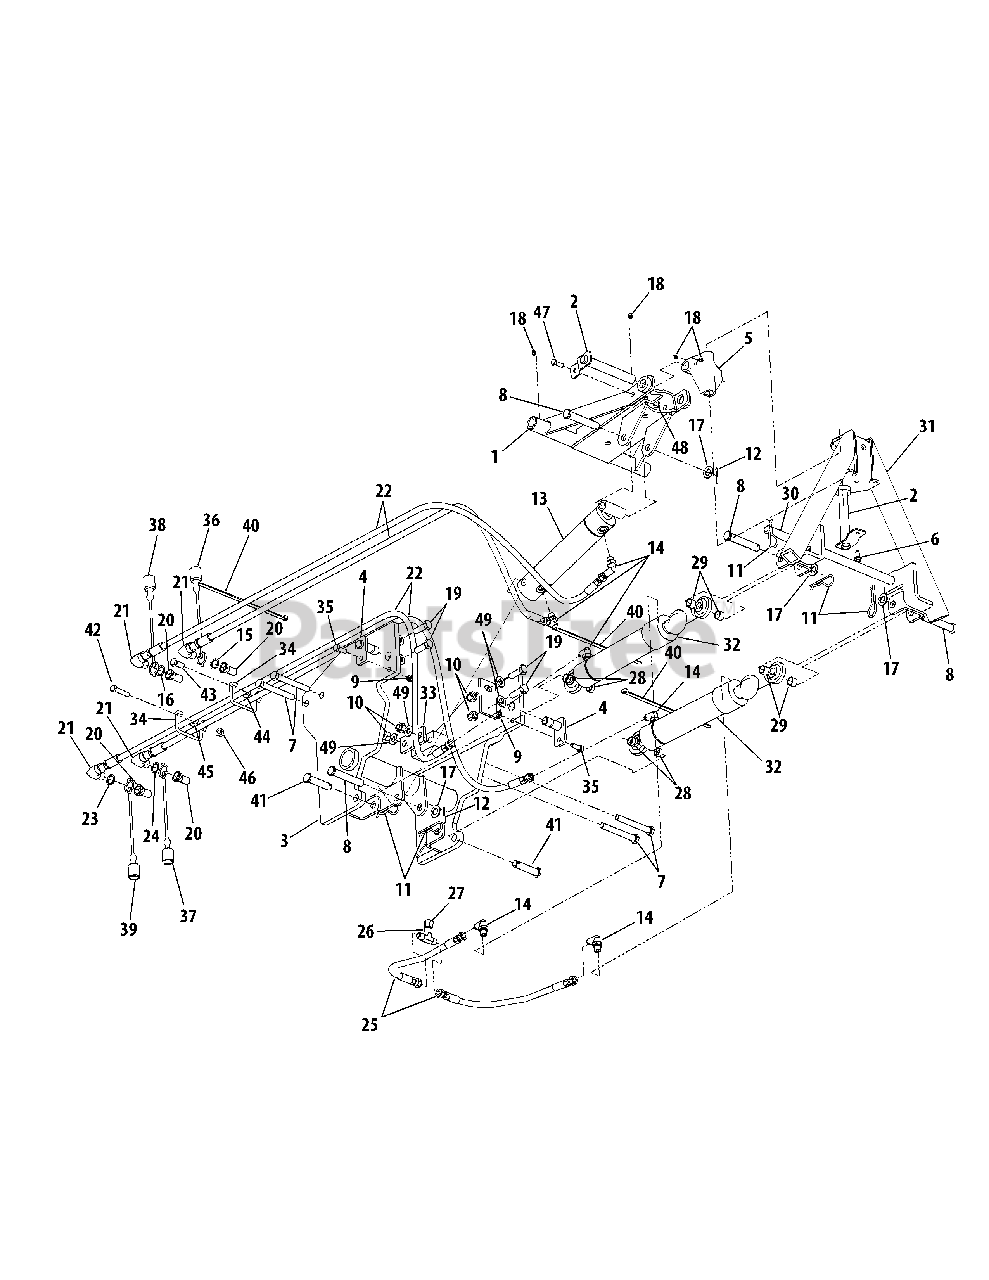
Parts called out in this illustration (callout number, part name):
2	Pin, Front Hitch
3	Brace, Front Hitch
4	Pin, Hitch Pivot
5	Housing, Pivot
6	Screw, Hex Wash. Hd Tap, 5/16-18 x .75
7	Screw, Hex Cap, 1/2-13 x 4.0 Gr5
8	Pin, Clevis, .625 x 3.45
9	Screw, Hex Cap, 5/8-11 x3.75 Gr5
10	Nut, Hex Insert Lock, 1/2-13 GrB
11	Pin, Internal Cotter
12	Pin, Cotter, 1/8 x 1.25
13	Cylinder, Hitch Lift
14	Fitting, 90 Degree
15	Washer, Indicator, Green
16	Washer, Indicator, Blue
17	Washer, Flat, .635 x 1.125 x .09
18	Fitting, Lube
19	Screw, Hex Cap, 1/2-13 x 1.5 Gr5
20	Coupling, Hydraulic Male
21	Fitting, Elbow, 3/8
22	Hose, Hydraulic, 1/4 x 64.75
23	Washer, Indicator, Red
24	Washer, Indicator, Yellow
25	Hose, Hydraulic
26	Fitting, Tee
27	Cap, Fitting
28	Spacer, Short Cylinder
29	Spacer, Long Cylinder
30	Rod, Hitch Lock
31	Frame, Hitch
32	Cylinder, Hitch Angle
33	Spacer, Front Hitch
34	Rod, Hose Support
35	Screw, Hx Cp Lk, 3/8-16 x 1.5 Gr5
36	Plug, Hyd. Coupler, Green
37	Plug, Hyd. Coupler, Yellow
38	Plug, Hyd. Coupler, Blue
39	Plug, Hyd. Coupler, Red
40	Tie, Cable, 36" Long
41	Pin, Clevis, .618 x 2.75
42	Screw, Hex Cap, 3/8-16 x 1.75 Gr5
43	Rod, Hose Support
44	Nut, Hex Insert Lock 5/8-11, Gr5
45	Washer, Flat, .406 x .875 x .105
46	Nut, Hex Flange Lock, 3/8 -16 GrF
47	Screw, Hex Cap, 5/16-18 x 1.0 Gr5
48	Nut, Hex Insert Flnge Lock, 5/16-18 Gr F
49	Washer, Flat, .51 x 1.0 x .125
